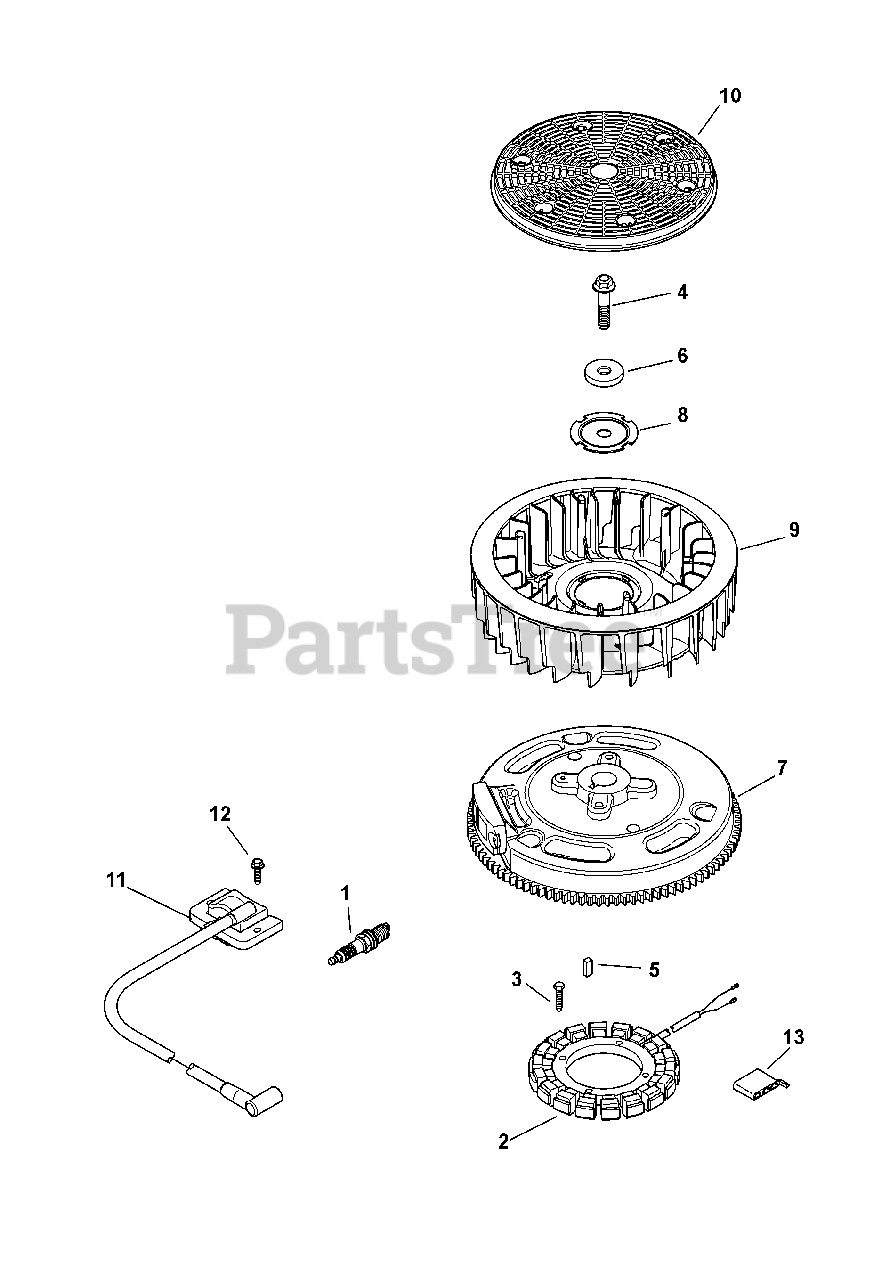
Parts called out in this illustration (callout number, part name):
1	Spark Plug
2	15 Amp Stator Kit
3	Screw, M5 x 0.8 x 25
4	Hex Flange Screw
7	Flywheel Assembly
8	Fan Mounting Plate
9	Fan
11	Module Ignition Kit
12	Screw, M5 x .8 x 20
